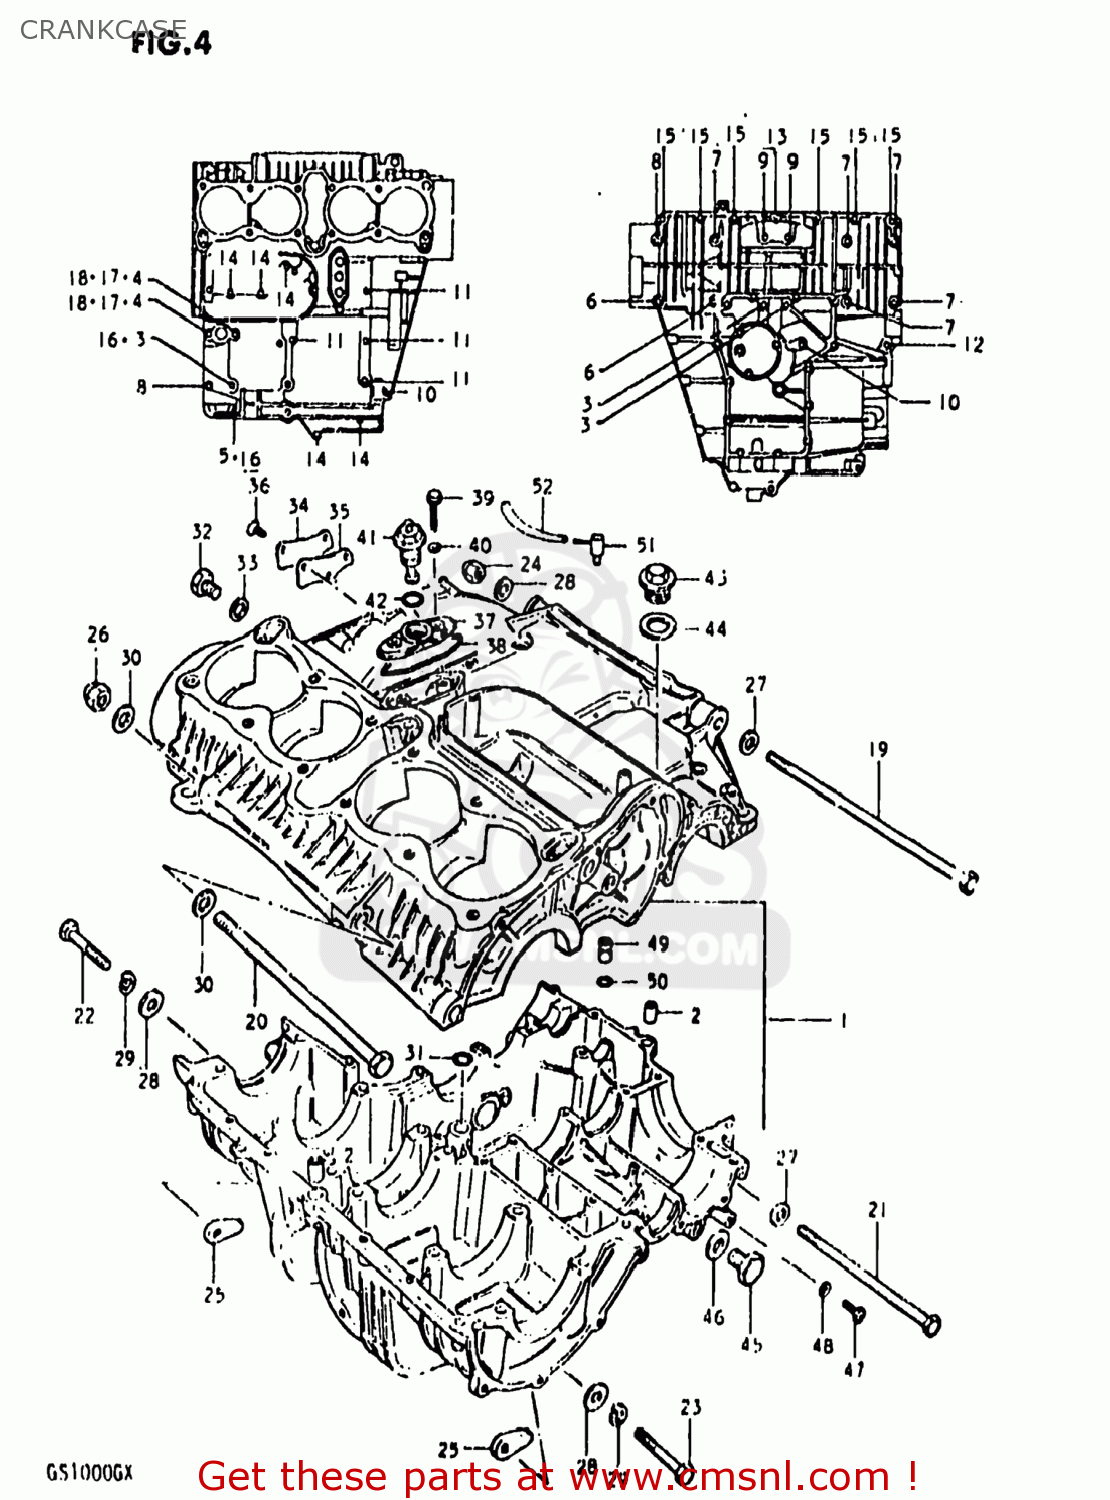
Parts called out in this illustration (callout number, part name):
1	CRANKCASE SET
2	PIN
3	BOLT
4	BOLT
5	BOLT
6	BOLT
7	BOLT 8X90
8	BOLT 8X65
9	BOLT
10	BOLT (6X90)
11	BOLT (6X75)
12	BOLT
13	BOLT ,6X50
14	BOLT,UNDER
15	BOLT 6X35
16	NUT
17	NUT
18	GASKET 8.2X14X1 (NAS)
19	BOLT 10X270
20	SHAFT,REAR SWING ARM
21	BOLT(10X165)
22	BOLT 10X60
23	BOLT (10X50)
24	NUT
25	NUT
26	NUT 12MM
27	WASHER(10.5X20X3.2)
28	WASHER
29	LOCK WASHER
30	WASHER
31	O RING(D:3.2,ID:12.9)
32	PLUG (14X12)
33	GASKET(14X19.2X2) (NAS)
34	CAP,OIL GALLERY
35	GASKET,OIL GALLERY (MCA)
36	SCREW
37	HOUSING,OIL PRESSURE SWITCH
38	O RING,PRESSURE SWITCH HOUSING
39	BOLT
40	GASKET (NAS)
41	SWITCH ASSEMBLY
42	O RING(D:1.9,ID:18.8)
43	PLUG
44	GASKET
45	PLUG
46	GASKET(14X19.2X2) (NAS)
47	SCREW(6X10)
48	GASKET (NAS)
49	UNION
50	O-RING
51	BPLUG,BEVEL GEAR BREATHER
52	HOSE
